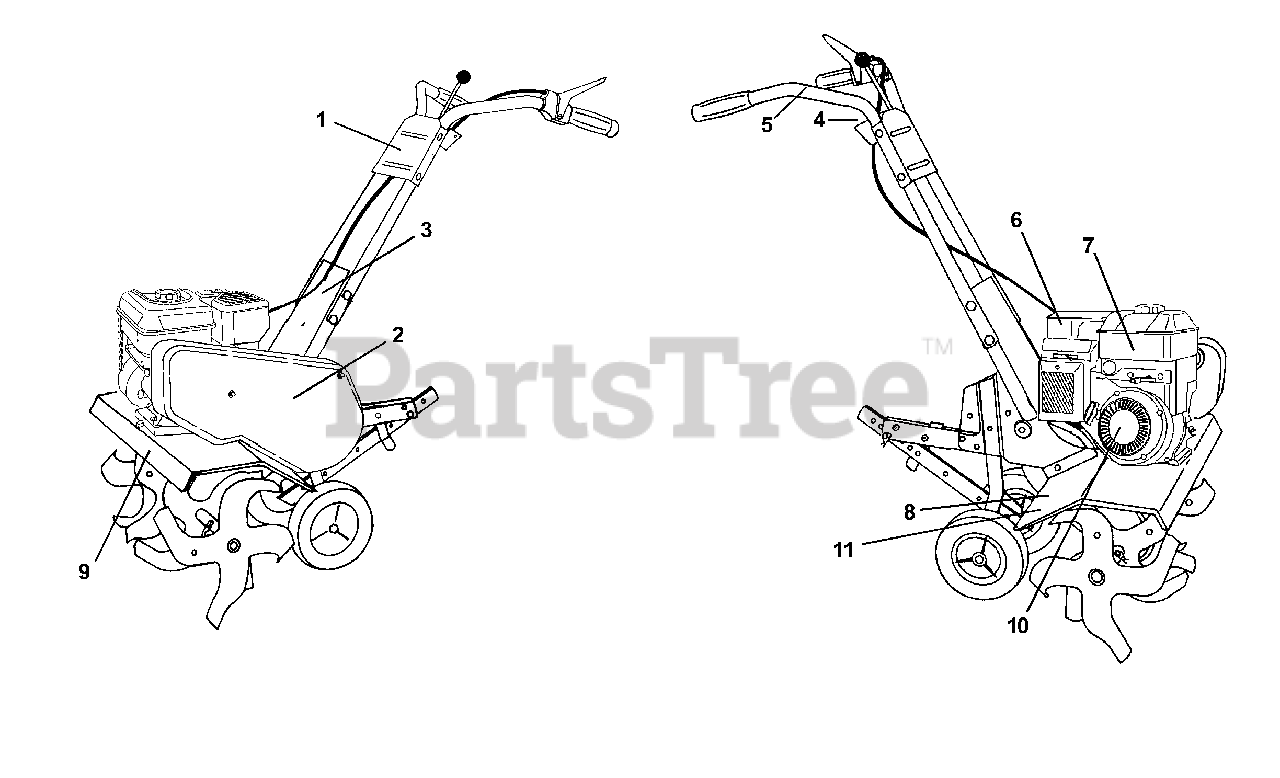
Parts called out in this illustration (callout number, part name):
1	Decal, Logo
2	Decal, Logo
3	Decal, HP, Reverse
4	Decal, Reverse, Tine Control
5	Decal, Hand Placement
6	Decal, Eng. Tiller
7	Decal, OHV. N-I/C
8	Decal, Warning, Rotating Tines
9	Decal, Hvy Duty
10	Decal, Rewind Intek
11	Decal, Tine Shield Wrng. Dom
